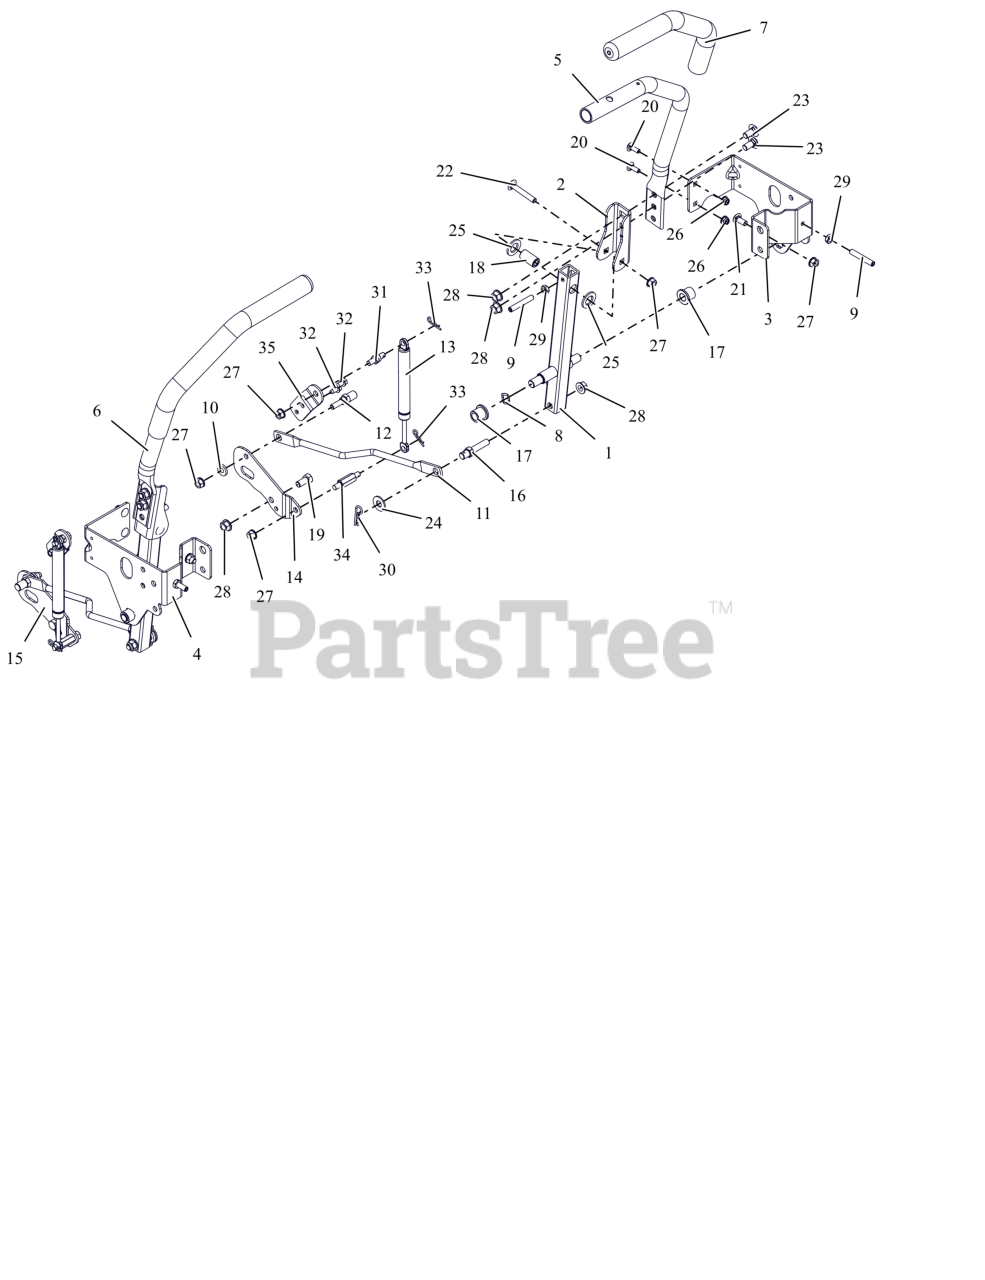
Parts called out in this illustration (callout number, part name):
1	WLDMT, LOWER CONTROL ARM (BLACK)
2	ARM, CONTROL -UPPER
3	BRKT, SPEED ADJ/SEAT PIVOT-LH (BLACK)
4	BRKT, SPEED ADJ/SEAT PIVOT-RH (BLACK)
5	WLDMT, CONTROL HANDLE -LH (BLACK)
6	WLDMT, CONTROL HANDLE - RH (BLACK)
7	GRIP, HANDLEBAR 15" FOAM
8	WAVE WASHER .531X.781X.125FH
9	SCR-SET, .312-18X2.000 SS
10	BSHG-FLG .316X.430X.225X.750
11	LINKAGE, STEERING
12	STUD, STEERING LINK-REAR
13	DAMPER, STRAIGHT MOUNT
14	PLATE, DAMPER RH
15	PLATE, DAMPER
16	STUD, STEERING LINK -FRONT
17	BHSG-FLG .500X.750X.750X.125
18	BSHG, -SLV .342 X .627 X 1.171
19	BLT,HEX .38-16X.75 G5 ZCC
20	BLT, RHSN .25-20X.750 G5 ZCC
21	BLT, RHSSN.31-18X.750 G5 ZCC
22	BLT, RHSSN .31-18X2.00 G5 ZCC
23	BTL,RHSSN .375-16 X 0.75 G5 FPB
24	WSHR,FLT .438X1.00X.083 ZCC
25	WSHR, FRICTION
26	NUT,NYL-FLG .25-20 GF ZCC
27	NUT,LK-CTR-FLG .31-18 GF ZCC
28	NUT-LK-CTR-FLG .375-16 GF ZCC
29	NUT-JAM .312-18 G2 ZCC
30	PIN, HAIR #203 .09X1.50 ZCC
31	COUPLER, DAMPER MOUNT
32	SCR-TAP .25-20X.50 HWH ZCC
33	PIN, HAIR #213 .08X1.19 ZCC
34	COUPLER, DAMPER MOUNT (LOWER)
35	PLATE, DAMPER TOP MOUNTING (BLACK)
